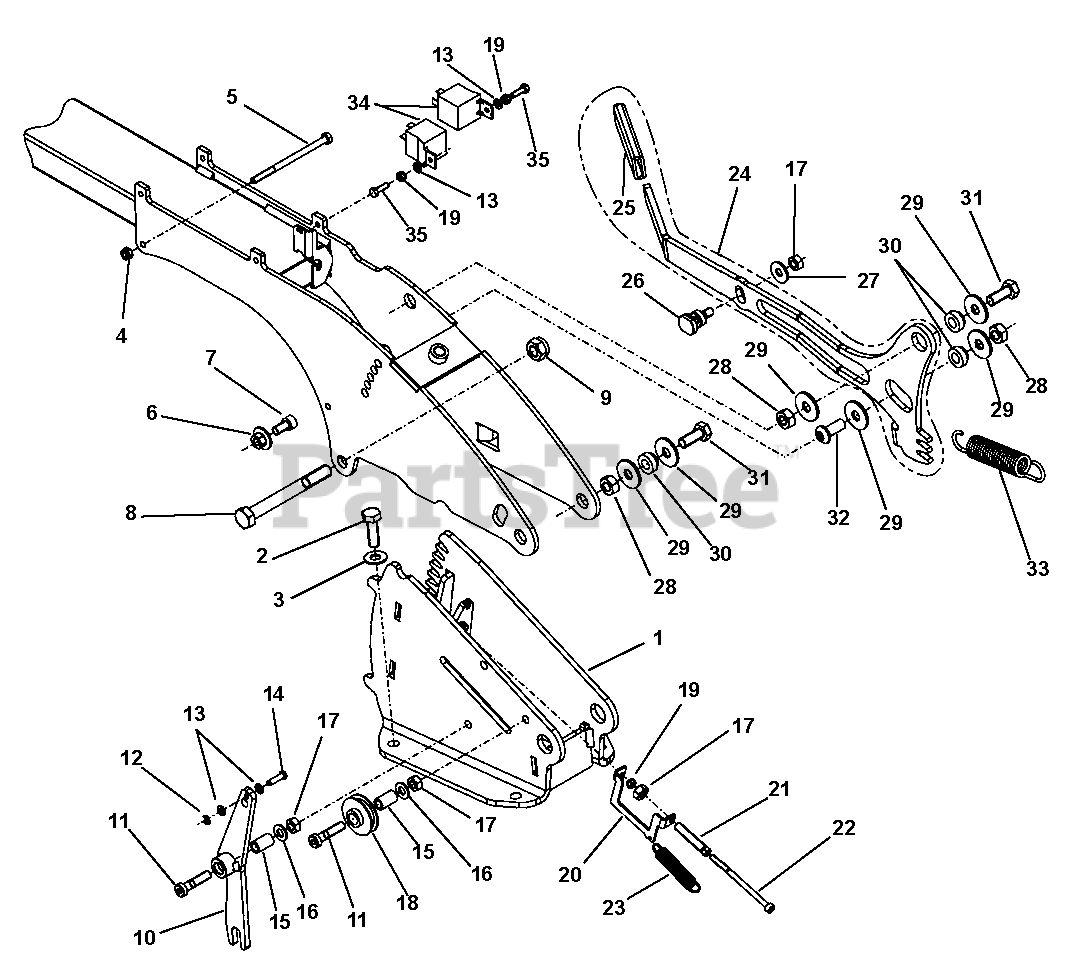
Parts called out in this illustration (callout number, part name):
1	Support, Handlebar
2	Bolt, Hex D933 M10 x 30
4	Nut, Lock D985 M6
5	Bolt, Hex D931 M6 x 100
6	Nut, Lock M8
7	Screw D912 M8 x 16
8	Bolt, Hex D931 M12 x 110
9	Nut, Lock M12
10	Lever, Advance
11	Bolt, Cylindric D7984 M4 x 35
12	Washer, Lock
13	Washer, D125 5.3 x 10 x 1
16	Washer D125 M8
17	Nut, Hex D934 M8
19	Nut, Lock M5
21	Screw, Hollow
22	Bolt, Cylindric D912 M5 x 80
23	Spring, Tension
25	Cover, Grip
27	Washer, M8
28	Nut, Lock D934 M10
29	Washer, D9021 10,5 x 30 x 2,5
30	Bearing Bushing
31	Bolt, Hex D933 M10 x 25
32	Screw ISO 7380 M10 x 25
33	Spring, Tension, 3.2/19.3 x 122
35	Bolt, Hex D933 M5 x 16
